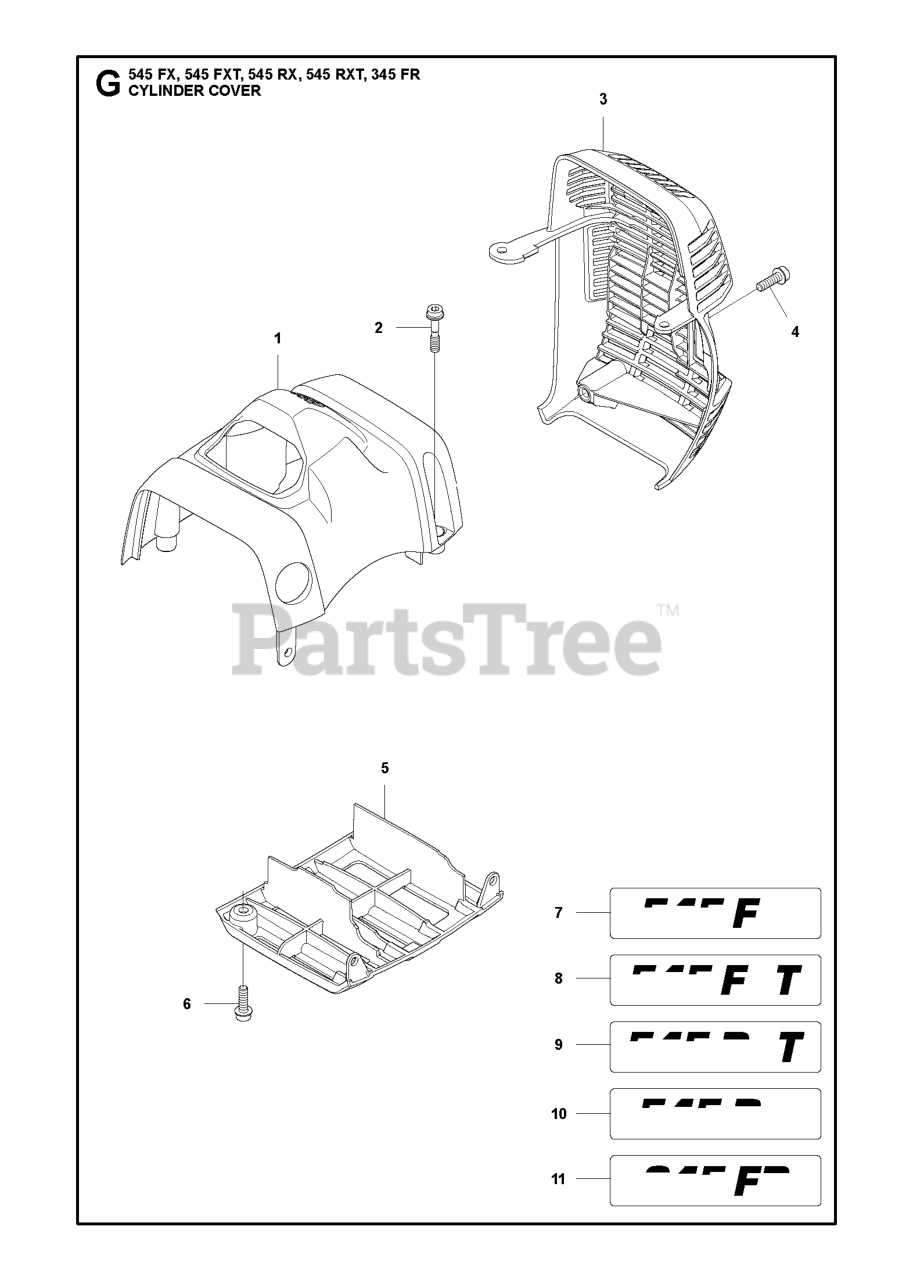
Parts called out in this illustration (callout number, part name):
1	CYLINDER COVER
2	SCREW IHSCFMO
3	HEAT PROTECTOR
4	SCREW IHSCFM
5	PROTECTIVE COVER
6	SCREW IHSCFM
7	LABEL
8	LABEL
9	LABEL
10	LABEL
11	LABEL
